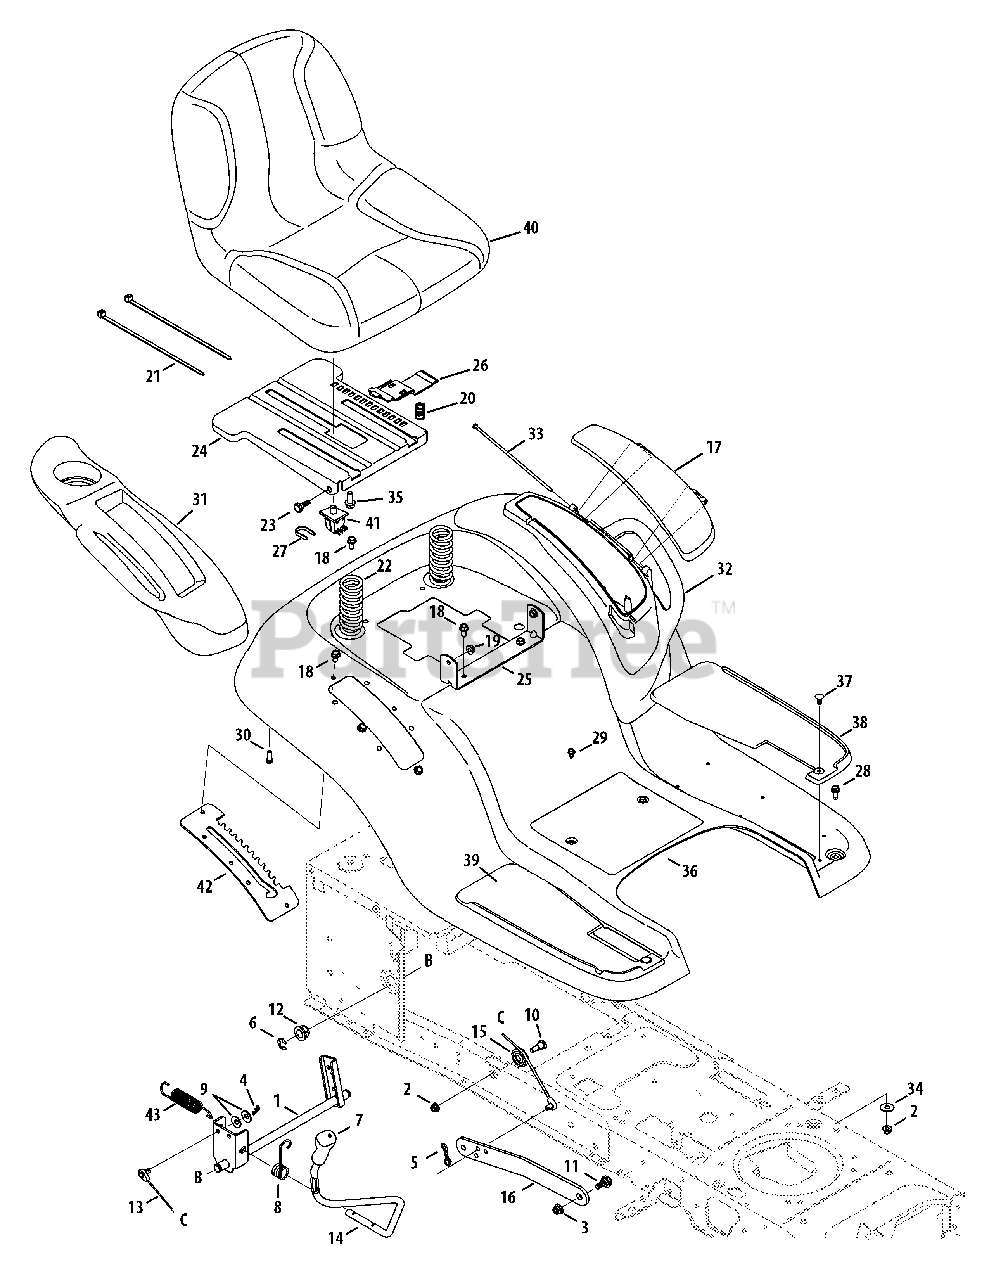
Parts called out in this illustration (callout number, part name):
1	Shaft Ass’y, Lift
2	Nut, Flange Lock, 5/16-18, Grf
3	Nut, Flange Lock, 3/8-16, Grf
4	Pin, Cotter, .072 Dia. x 1.13
5	Pin, Cotter, Bow-Tie 72
6	Ring, E Type, .625 Dia. Shaft
7	Grip, Handle, Cub, .50 ID
8	Spring, Torsion
9	Washer, Spring, .401 x .870 x .063
10	Screw, Shoulder, .437 x .470, 5/16-18
11	Bolt, Shoulder, .50, 3/8-16
12	Bearing, Hex Flange
13	Cable, Lift, 16.16
14	Handle, Lift,
15	Pulley, Roller, Cable
17	Door, Cover, Fender
18	Screw, Self-tapping, 5/16-18, .750,
19	Nut, Flange Lock, 5/16-18, Gr5, Sd Lk
20	Spring, Compr’, .68 x 1.065 x .055
21	Cable, Tie, 3/16 x .05 x 7.4
22	Spring, Comprs, 1.50 x 3.90 x .200
23	Screw, Shoulder, .437 x .268, 5/16-18
24	Bracket, Mounting, Seat
25	Bracket, Pivot, Seat
26	Lever, Seat Adjustment
27	Clip, Retaining, Switch
28	Hex Screw, 5/16-18, .75, Gr5, Std
29	Screw, Self-tapping, 1/4-20, 0.500,
30	Screw, HL, 1/4-15, 0.750,
31	Cover, Fender, RH
32	Cover, Fender, LH
34	Washer, Flat .344 x 1.00 x .063
35	Hex Flange Bolt, 3/8/16, .875, Gr5
36	Fender, Cub Hydro
37	Clip, Ratchet, .250 Dia
38	Pad, Foot, LH
39	Pad, Foot, RH
40	Seat, High Back Cloth, Cub
41	Switch, Seat
42	Bracket, Lift
43	Spring, Extension, 1.15 OD x 5.99
